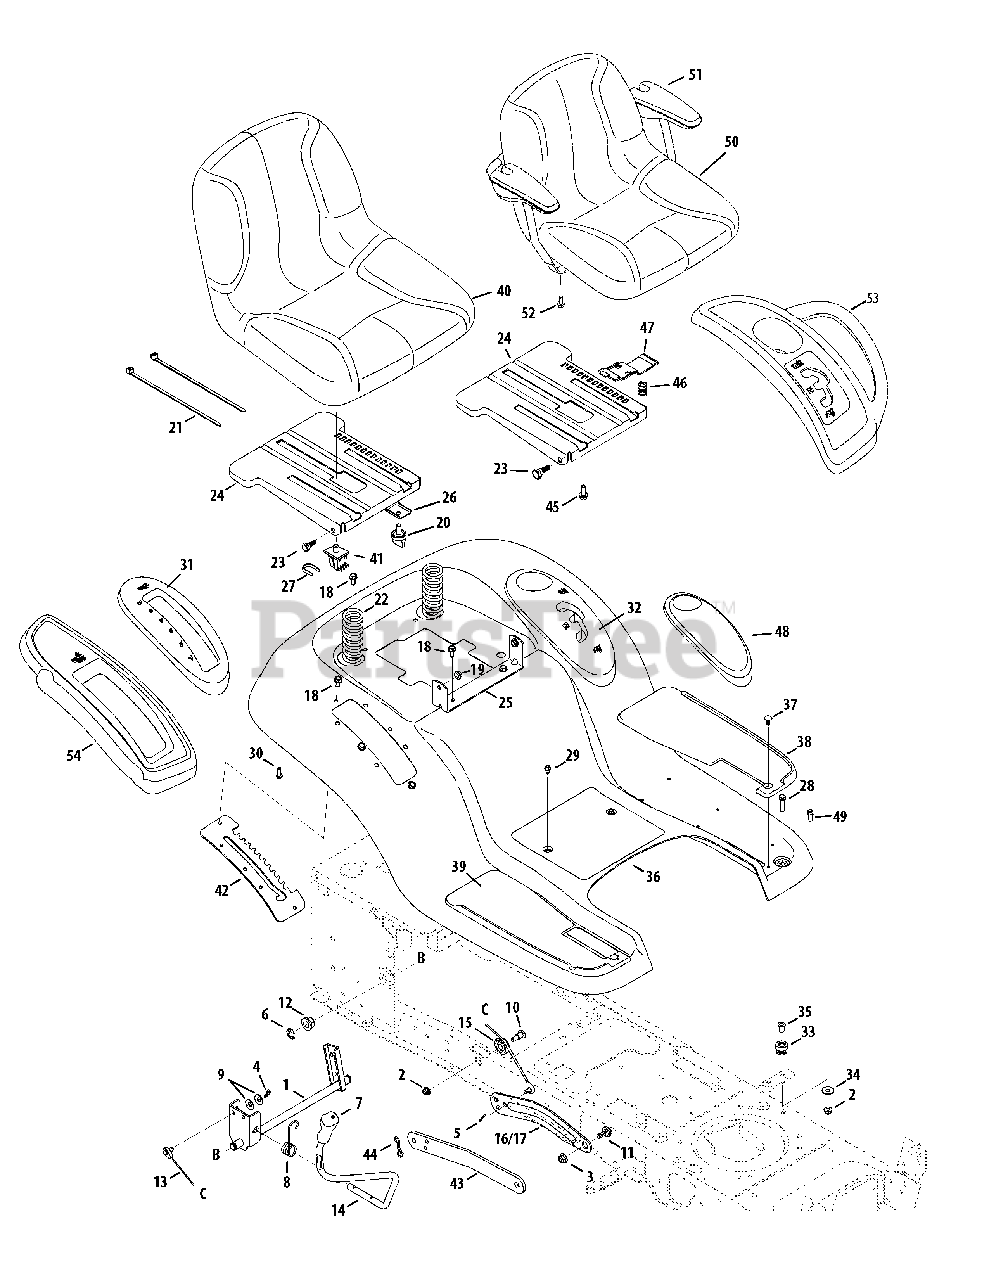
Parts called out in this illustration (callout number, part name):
1	Lift Shaft Ass’y
2	Flange Locknut 5/16-18 Gr. F, Nylon
3	Flange Lock-Nut 3/8-16 Gr. F Nylon
4	Int. Cotter Pin .072 x 1.13" Lg.
5	Bow-Tie Cotter Pin
6	E-ring .625 Shaft
8	Tor sion Spring
9	Cupped Washer .375 ID x .870 OD x .063
10	Shoulder Screw. .437 Dia x .47
11	Shoulder Screw .500 x .25 (46"/50")
11	Shoulder Bolt 3/8-16 x .625 (38"/42")
12	Hex Flange Bearing .630 ID
13	Lift Cable, 16.16
15	Roller Pulley
18	Hex Wash Hd. Tapp Screw. 5/16-18 x .75
19	Hex Flange L-Nut 5/16-18
22	Compression Spring 1.50 x 3.9 x .20
23	Shoulder Screw
26	Seat Bracket, Knob adjustment
27	Switch Retaining Clip
28	Hex Bolt 5/16-18 x 1.25
29	Hex Wash S-Tapp Screw 1/4-20 x .50
30	Hex Tapp Screw 1/4 x .75" Lg.
31	Lift Lever Cover
32	Shift Lever Cover
33	Grommet .4375 ID x .75
34	Flat Washer .344 ID x 1.0
35	Flange Spacer .3125 x .4375 x .625
37	Foot Pad Clips
40	Seat, High Back, Black
40	Seat, High Back, Yel low
40	Seat, High Back Cloth, Black Cub
40	Seat, Med Back Cloth, Black Cub
42	Lift Bracket 6 positions (w/Electric pto)
44	Bow-Tie Cotter Pin (46")
45	Hex. Hd. Flg. Screw. 3/8-16 x .875
46	Compression Spring .68 x 1.065 x .055
47	Seat adjustment Lever
48	Cover (Hydrostatic Models only)
49	Hex Wash. Hd. Screw. 5/16-18 x .75 Gr. F Nyl.
50	Seat, High Back, Black (w/arm rest option)
51	Arm Rest (incl. R&L)
52	Pan TT Screw 5/16-18 x .75
53	Fender Cover LH
54	Fender Cover RH
55	Car riage Bolt 14-20 x 1.0
56	Sems Hex Nut 1/4-20
